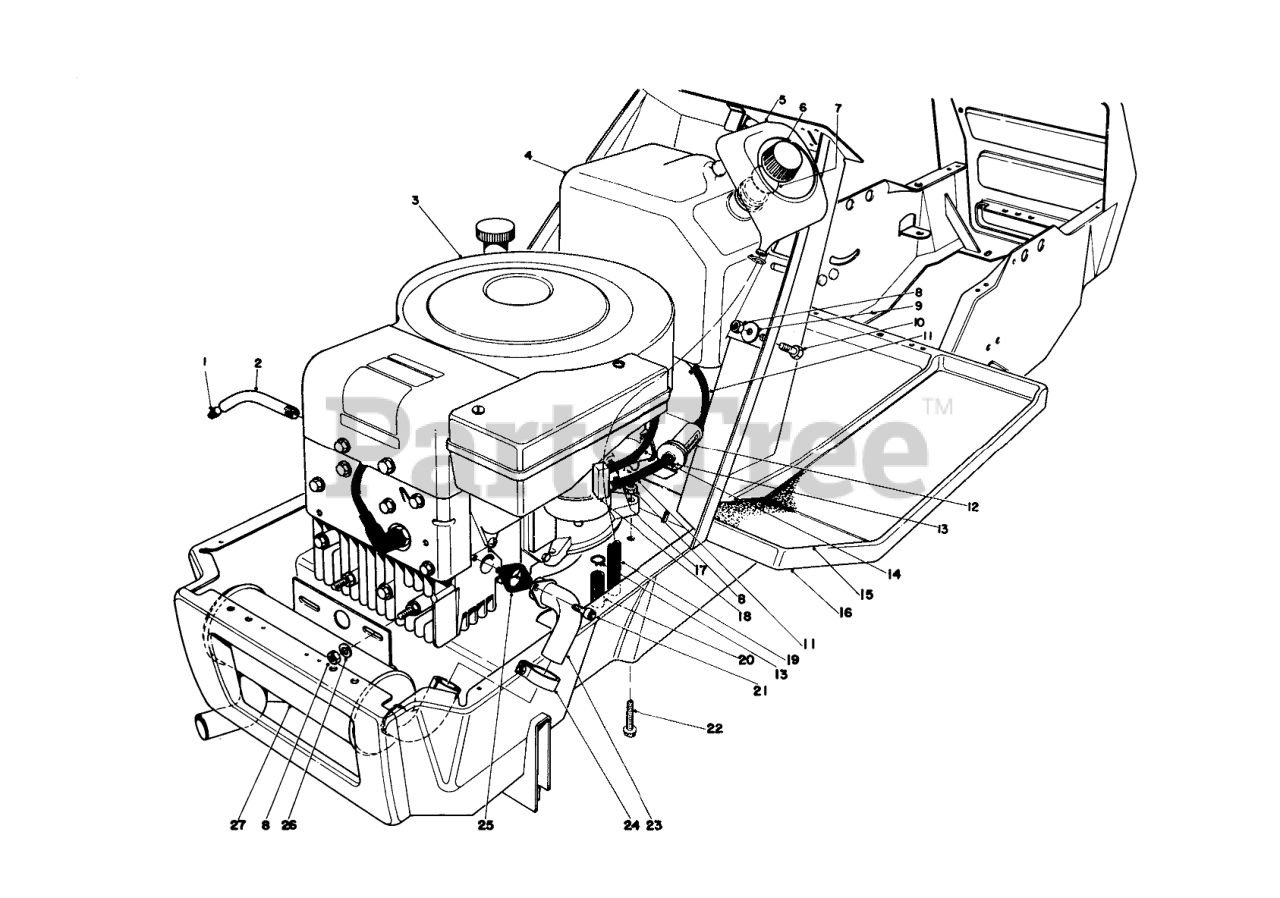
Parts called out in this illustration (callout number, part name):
1	PLUG-PIPE, SQH
2	OIL DRAIN TUBE
3	Engine
4	Gas Tank Assembly (Incl. Ref. #5)
5	Funnel Overflow
6	Gas Cap Assembly (Incl. Ref. #7)
7	Gasket Gas Cap
8	NUT-LOCK, CONE
9	WASHER
10	SCREW-HH
11	GAS HOSE
12	Fuel Filter
13	HOSE CLAMP
14	Gas Return Hose
15	LH FOOT TREAD
16	Frame
17	Clamp
18	Fitting Carburetor
19	Hose Funnel
20	Hose Carburetor Drain
21	SCREW-HSH
22	SCREW-HH
23	10 HP EXHAUST PIPE WA
24	MUFFLER CLAMP
25	Exhaust Gasket
26	WASHER-PLAIN
27	EXHAUST MUFFLER 10 HP
